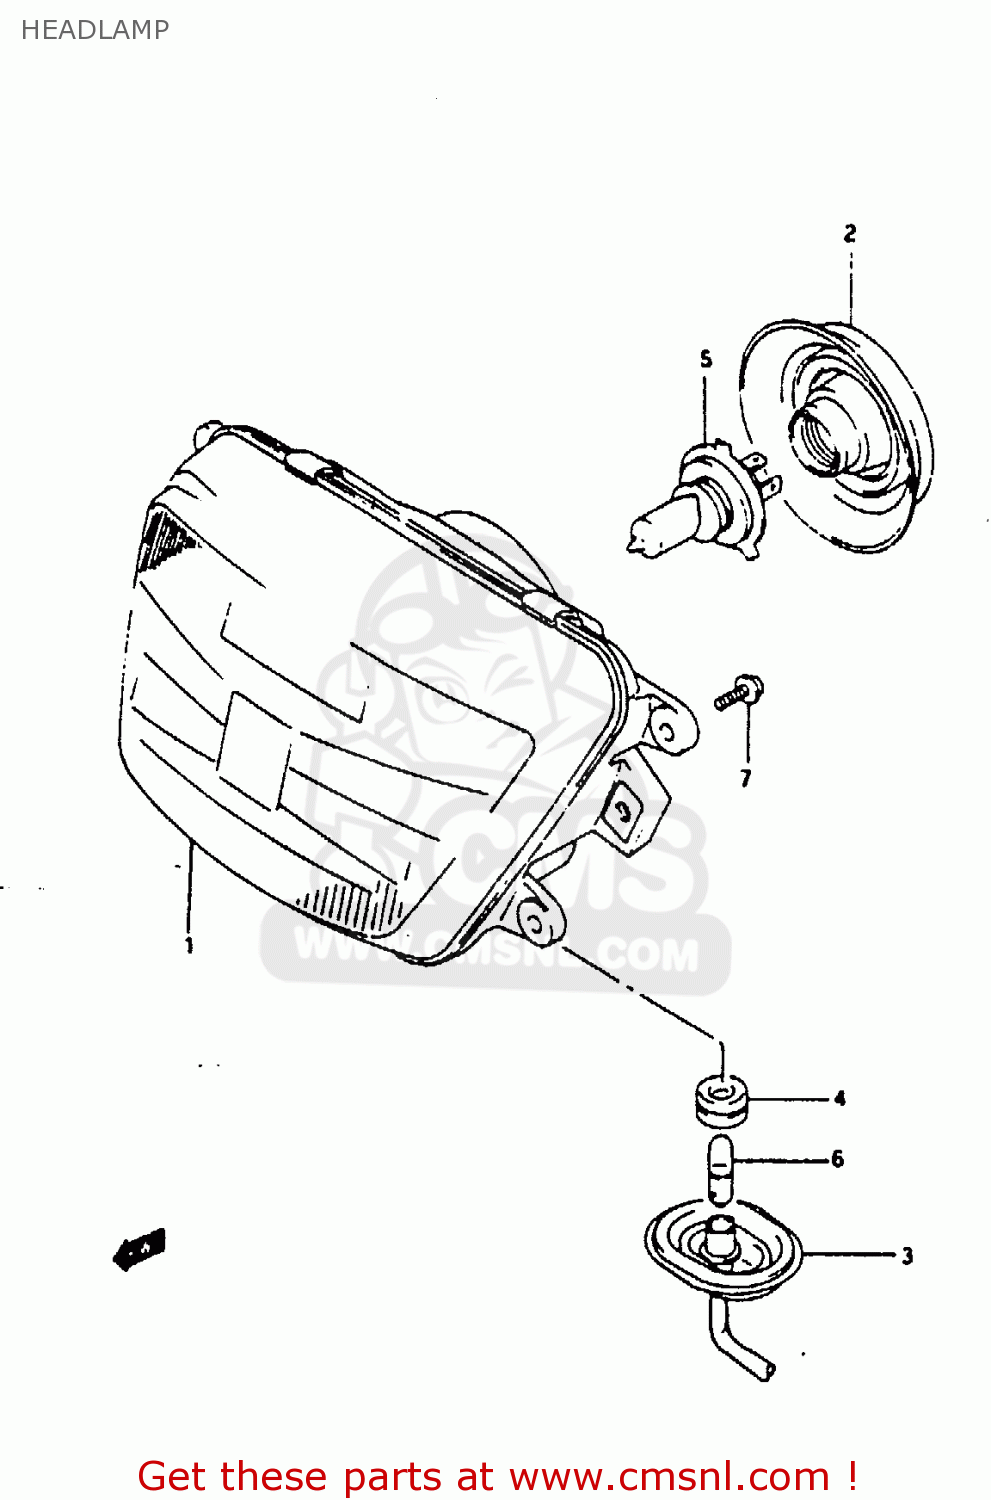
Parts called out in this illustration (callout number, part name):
1	UNIT, HEADLAMP
2	COVER,SOCKET
3	SOCKET
4	JOINT,RUBBER
5	BULB(12V60/55W,H4)
6	BULB(12V4W)
7	SCREW
